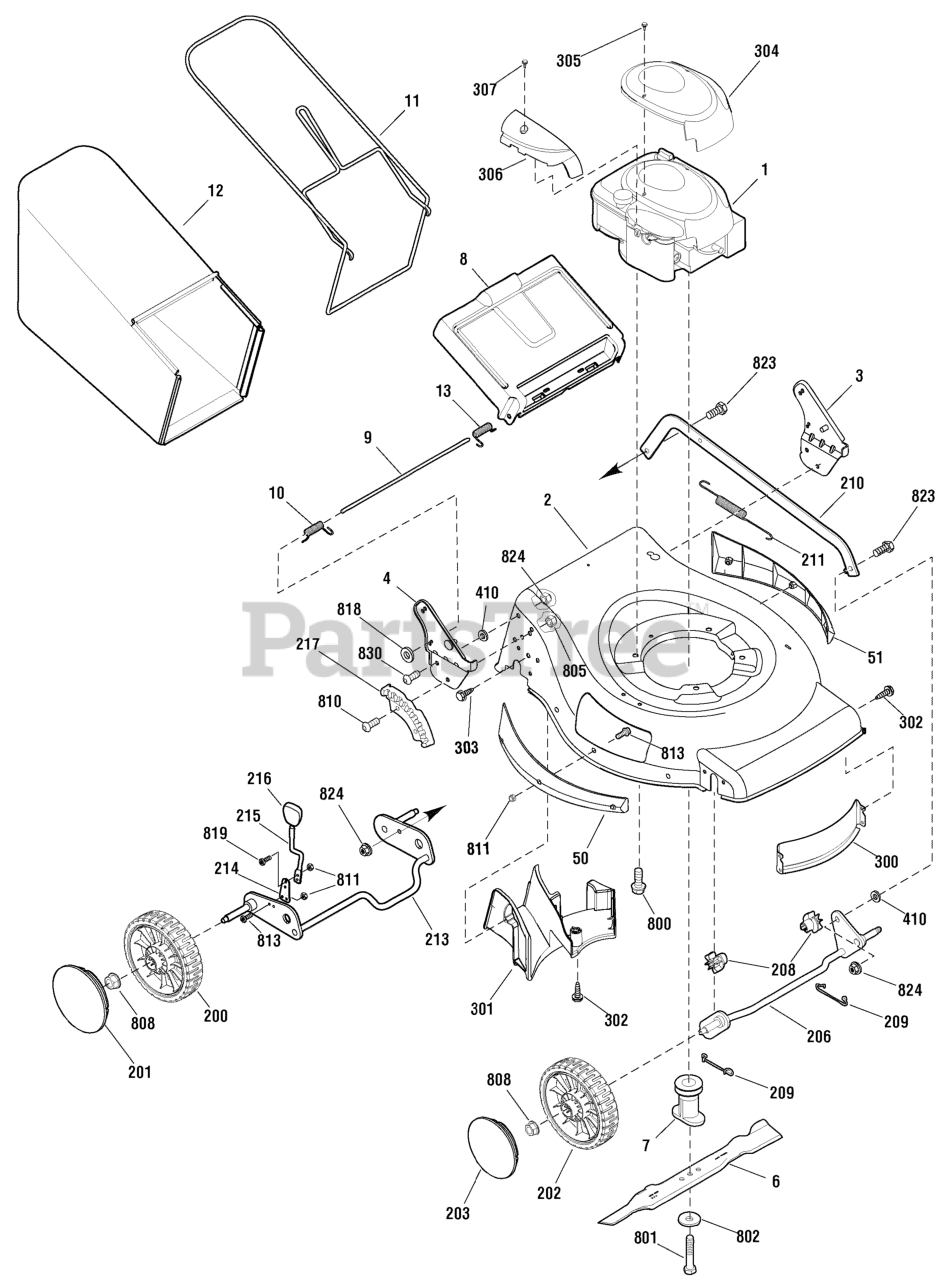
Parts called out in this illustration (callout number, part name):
1	* ENGINE, 6.75GT Briggs & Stratton
2	* MOWER HOUSING
3	BRACKET ASSEMBLY, Left Handle
4	BRACKET ASSEMBLY, Right Handle
6	BLADE, 19"
7	BLADE ADAPTER ASSEMBLY
8	DOOR, Rear
9	ROD, Rear Door
10	SPRING, Torsion Rear Door, Right
11	FRAME ASSEMBLY
12	BAG ASSEMBLY
13	SPRING, Torsion Rear Door, Right
50	SIDE GUARD, Right
51	SIDE GUARD, Left
200	WHEEL, Rear, Complete
201	HUBCAP, Rear
202	WHEEL, Front
203	HUBCAP, Front
206	CROSSBAR ASSEMBLY, Front
208	BUSHING, Front Crossbar
209	SPRING, Clip Crossbar
210	LINK, Single Lever, High Wheel
211	SPRING, Extension
213	REAR CROSSBAR
214	SPRING, Adjuster
215	LEVER, Height Adjustment
216	KNOB, Adjuster
217	BRACKET, Height Adjuster
300	BAFFLE, Front
301	BAFFLE, Rear
302	SCREW, Pan Head, Taptite, 1/4-20 x 1/2
303	SCREW, Pan Head, Taptite, 1/4-15 x 5/8
304	COVER, Static
305	SCREW, Hex Washer Head
306	COVER, Control
307	SCREW, Pan Head
410	WASHER, Flat, .34
800	SCREW, Hex Head, 3/8-16 x 1
801	BOLT, Blade, 3/8-24 x 2
802	WASHER, Belleville
805	NUT, Nylock, M8 x 1-1/4
808	NUT, Flange, 3/8-16
810	BOLT, Hex Key Head
811	NUT, Nylock
813	SCREW, Torx Head, M5 x .8 x 14mm
818	PUSHNUT, 1/4
819	SCREW, Torx Head, M5 x .8 x 12.5mm
823	BOLT, Shoulder, 5/16-18 x 1
824	Nut, Flange, 5/16-18
830	CAPSCREW, 5/16-18 x 3/4
1000	DECAL KIT
